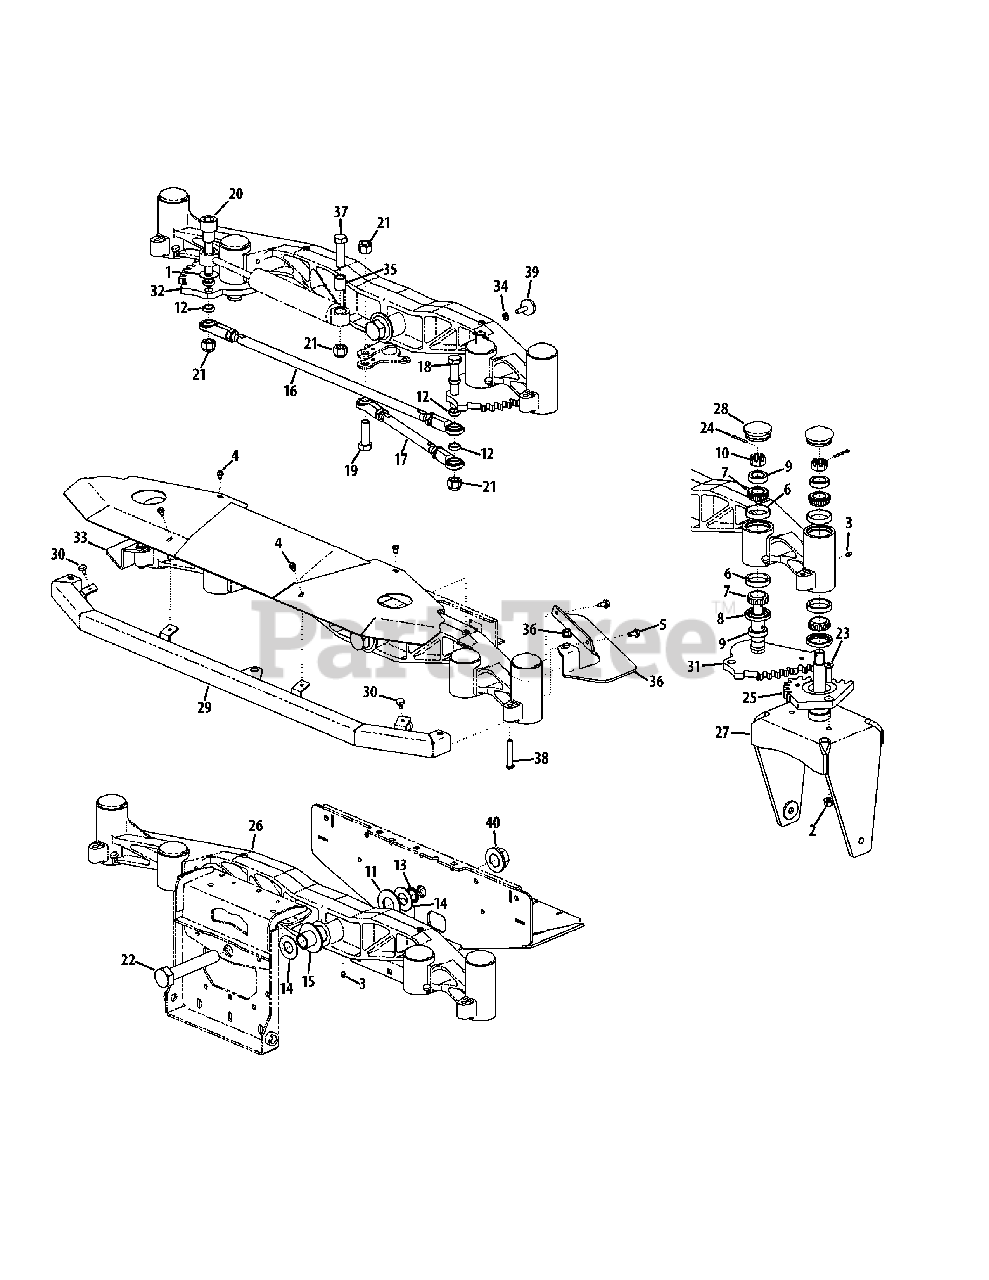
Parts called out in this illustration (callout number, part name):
1	Washer, .655 x 1.5 x .055
2	Flange Counter Lock Nut, 3/8-16
3	Grease Fitting, 1/4-28
4	Hex Flange Screw, 1/4-20 x .500
5	Flange Screw, 5/16-18 x .625
6	Bearing Cup, L44610
7	Cone Bearing, L44643
8	Seal, 14858
9	Seal Ring
10	Slot Nut, 3/4-16
11	Bell Washer, 1.25 x 2.50 x .180
12	Spacer, .635 x .880 x .312
13	Self-Lock External Retainer
14	Washer, 1.00 x 2.00 x .075
15	Spacer, 1.00 x 1.25 x 3.47
16	Tie Rod Assembly, 1/2-20 x 28
17	Tie Rod Assembly, 5/8-18 x 14
18	Hex Screw, 5/8-11 x 4.00
19	Hex Screw, 5/8-11 x 1.75
20	Shoulder Bolt, .872 x 1.030 x 2.88
21	Hex Lock Nut, 5/8-11
22	Hex Screw, 1-14 x 5.5
23	Hex Screw, 3/8-16 x 1.50
24	Cotter Pin, 5/32 x 1.25
25	Yoke Steering Gear
28	Axle Grease Cap
29	Axle Bumper Assembly
30	Rubber Bumper, .62 x .22
31	LH Steering Gear Assembly
32	RH Steering Gear Assembly
35	Spacer, .635 x .875 x 1.031
38	Screw, 3/8-16 x 2.25
39	Adjustable Skid Shoe
40	Flange Top Lock Nut, 1.0-14
